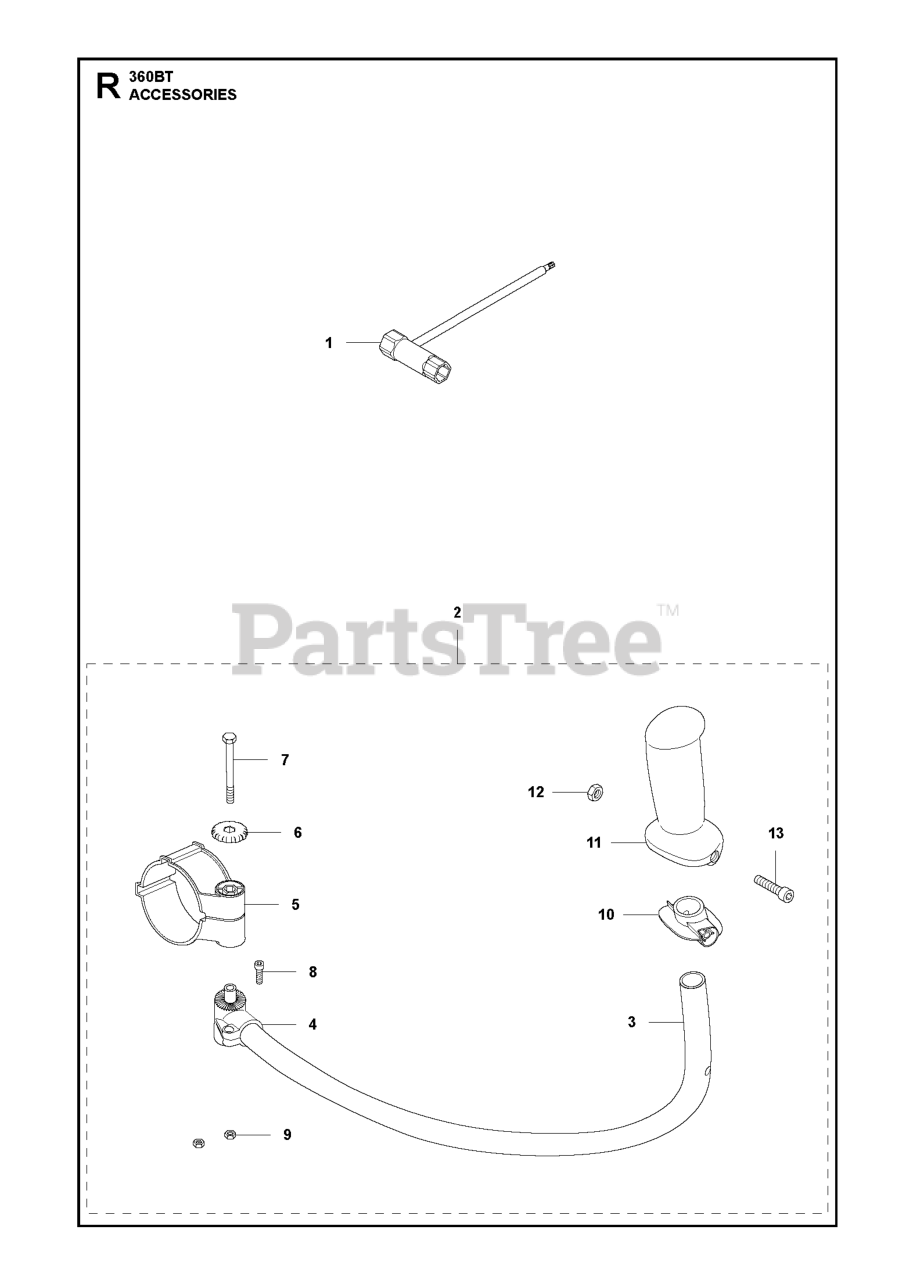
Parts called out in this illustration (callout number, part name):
2	HANDLE 170 BT
5	HANDLE HOLDER
8	SCREW MC6S 5X10
